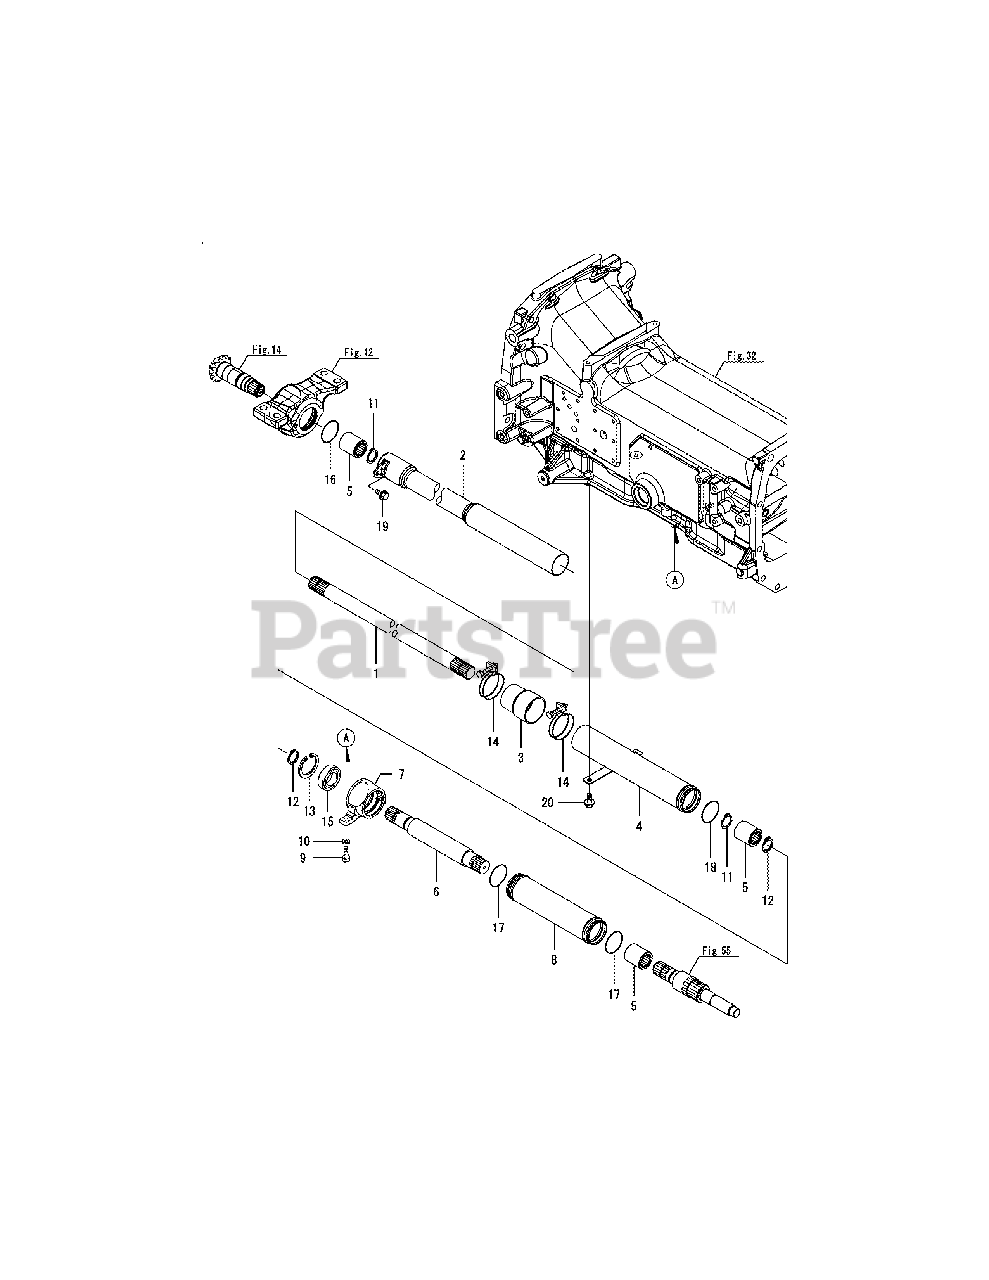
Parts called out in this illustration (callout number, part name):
1	SHAFT, PROPELLER
2	COVER, SHAFT FRONT
7	RETAINER, BEARING
8	COVER, SHAFT REAR
9	BOLT, REAMER 8X25
16	O-RING 1A G-50.0
17	O-RING 1A G-50.0
18	O-RING 1A G-50.0
19	BOLT M 8X 12 PLATED
20	BOLT M 8X 12 PLATED
